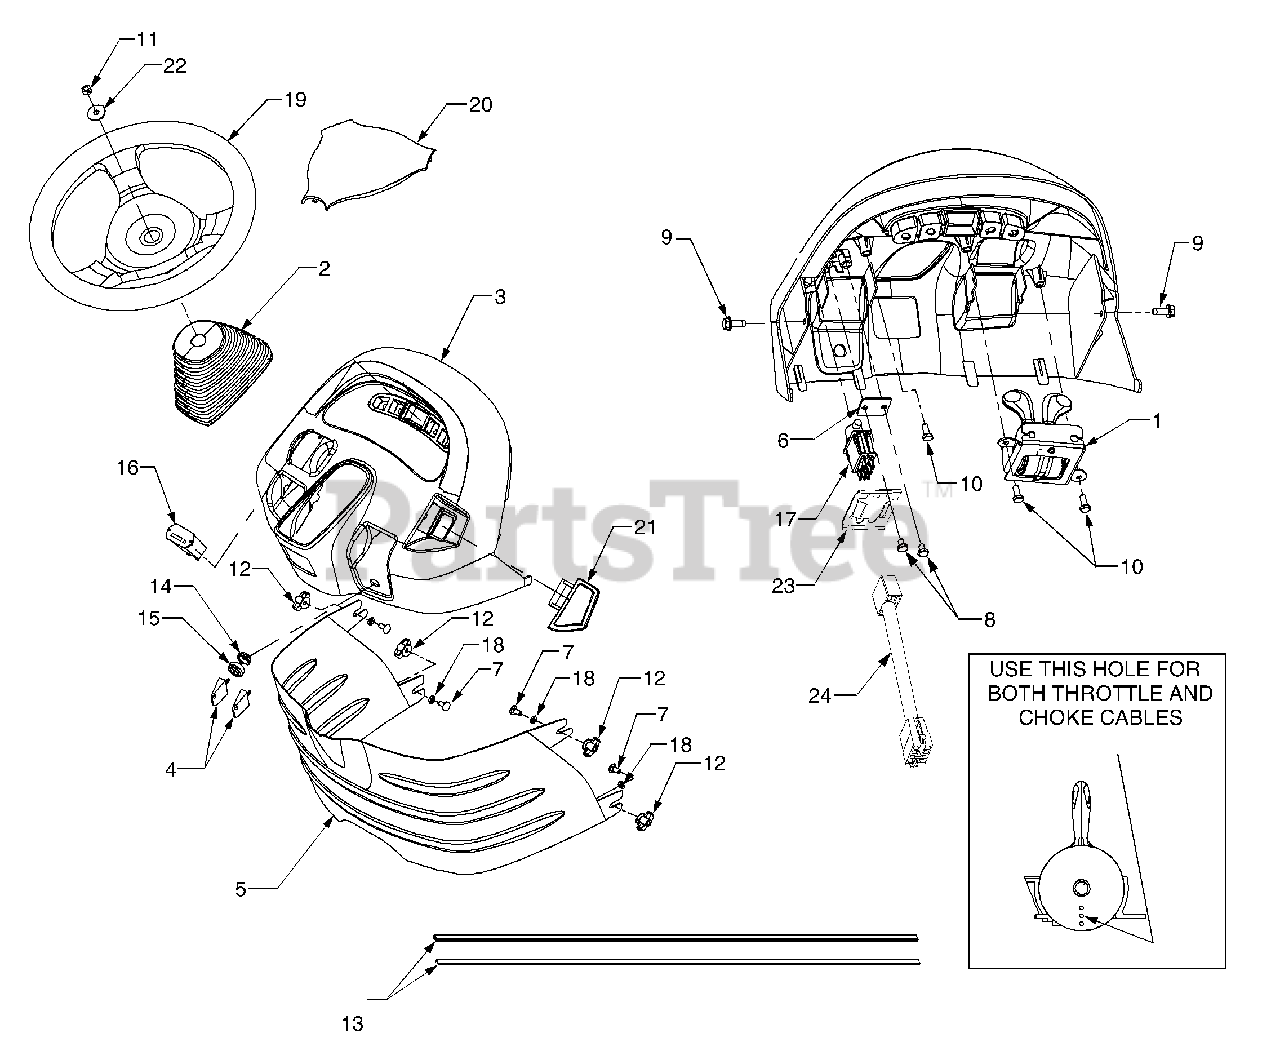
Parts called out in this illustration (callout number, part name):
1	Control Assembly, Throttle/Choke
2	Boot, Tilt Steer
3	Dash Panel
4	Key, Ignition
7	Carriage Bolt, 1/4-20 x .62
8	Screw, Hex Cap 1/4-20 x .375 GR5
9	Screw, Hex Wash. Hd. Tapp 5/16-18 x .75
10	Screw, Hex Cap 1/4-20 x .50 GR5
11	Nut, Hex Lock, 5/16-24
12	Wing Nut, 1/4-20 w/Bell Washer
13	Seal, Screen
14	Nut, Ignition Switch, 5/8-32
15	Cap, Ignition Switch
16	Hour Meter
17	Switch, PTO
18	Nut, Push
19	Steering Wheel
20	Cover, Steering Wheel
21	Handle, PTO Switch
22	Washer, Flat, .34 x 1.5 x .10
23	Bracket, PTO Switch Retainer
24	Harness, PTO Adapter
